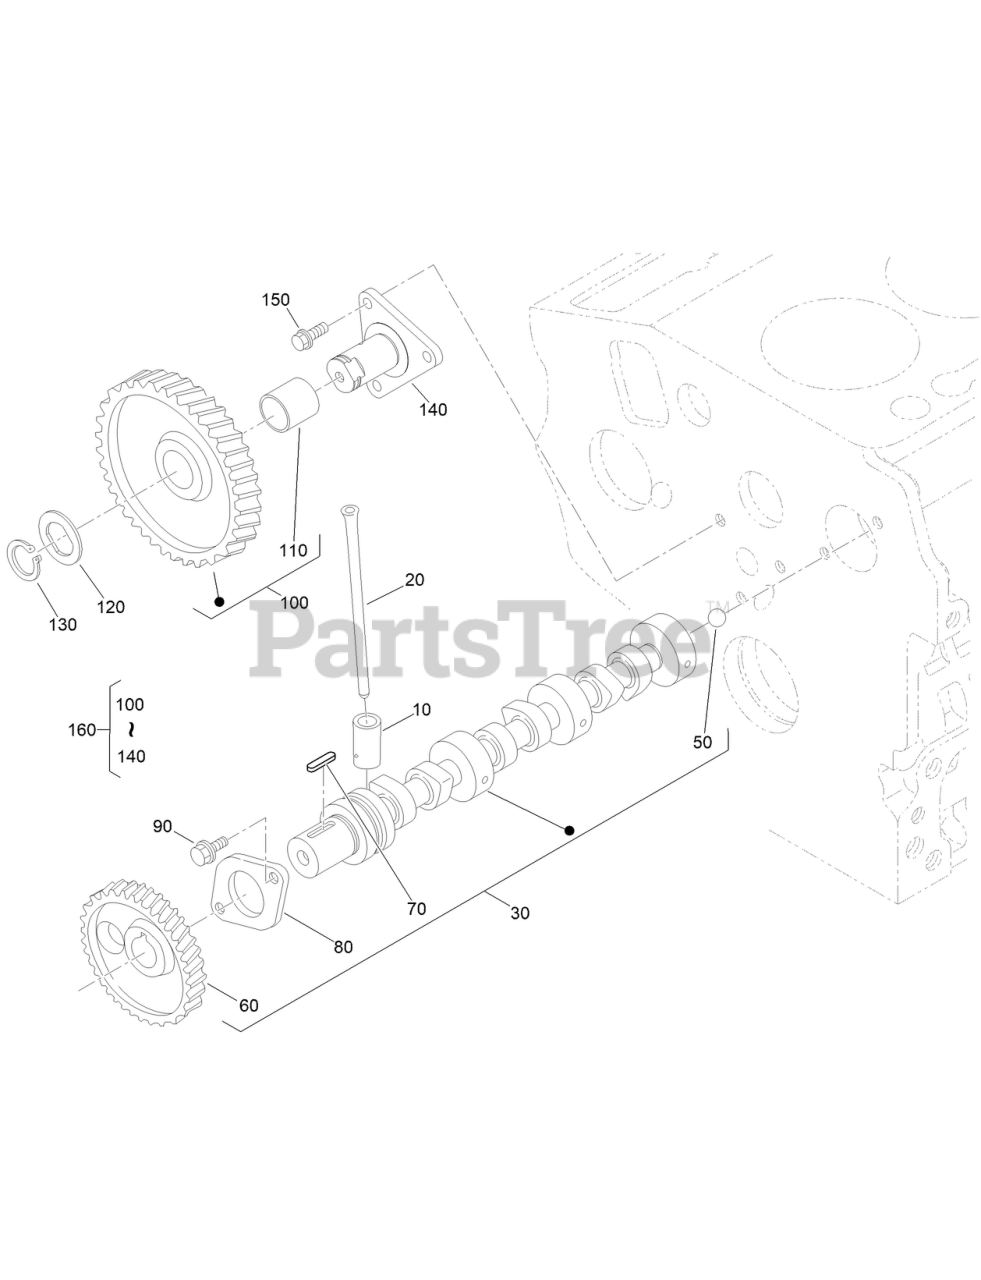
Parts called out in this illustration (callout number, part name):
10	TAPPET
20	ROD-PUSH
30	CAMSHAFT,ASSY
60	GEAR-CAM
70	KEY-FEATHER
80	STOPPER-CAMSHAFT
100	IDLE GEAR ASM
110	BUSHING
120	COLLAR-GEAR, IDLE
130	RING-SNAP
140	SHAFT-GEAR, IDLE
150	BOLT-FLANGE
160	IDLE GEAR ASM
